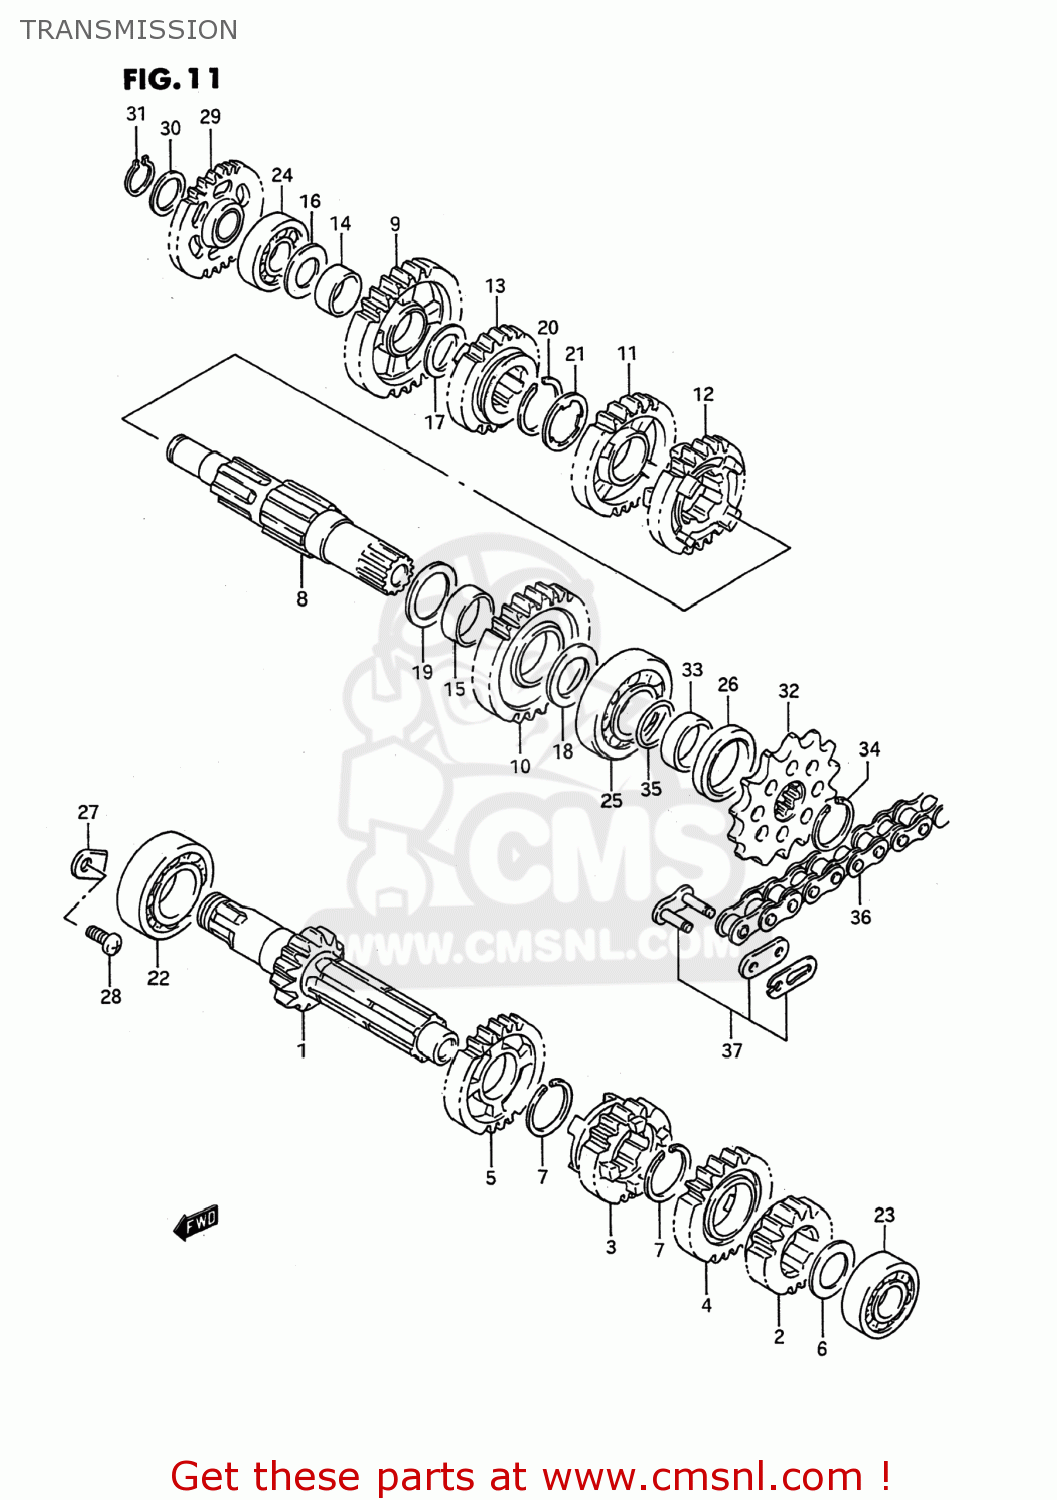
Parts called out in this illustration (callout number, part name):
1	SHAFT,COUNTER
2	GEAR,2ND DRIVE(NT:15)
3	GEAR,THIRD DRIVE (NT:16)
4	GEAR,FOURTH DRIVE (NT:22)
5	GEAR,5TH DRIVE(NT:22)
6	WASHER,THRUST
7	CIRCLIP
8	SHAFT,DRIVE
9	GEAR,1ST DRIVEN(NT:32)
10	GEAR,2ND DRIVEN(NT:26)
11	GEAR,THIRD DRIVEN
12	GEAR,FOURTH DRIVEN (NT:24)
13	GEAR,FIFTH DRIVEN (NT:19)
14	BUSH(20X24X10)
15	BUSH(25X28X10)
16	WASHER,THRUST
17	WASHER
18	THRUST WASHER
19	WASHER
20	CIRCLIP
21	WASHER,LOCK
22	BEARING(25X52X15)
23	BEARING(17X40X12)
24	BEARING(17X40X12)
25	BEARING(22X56X15)
26	SEAL,OIL(28X38X6)
27	RETAINER
28	SCREW
29	GEAR,KICK STARTER IDLE(NT:27)
30	SHIM
31	CIRCLIP
32	SPROCKET,ENGINE
33	SPACER,ENGINE SPROCKET
34	CIRCLIP
35	O RING(D:1.9,ID:21.8)
36	CHAIN,DRIVE
37	JOINT,CHAIN
